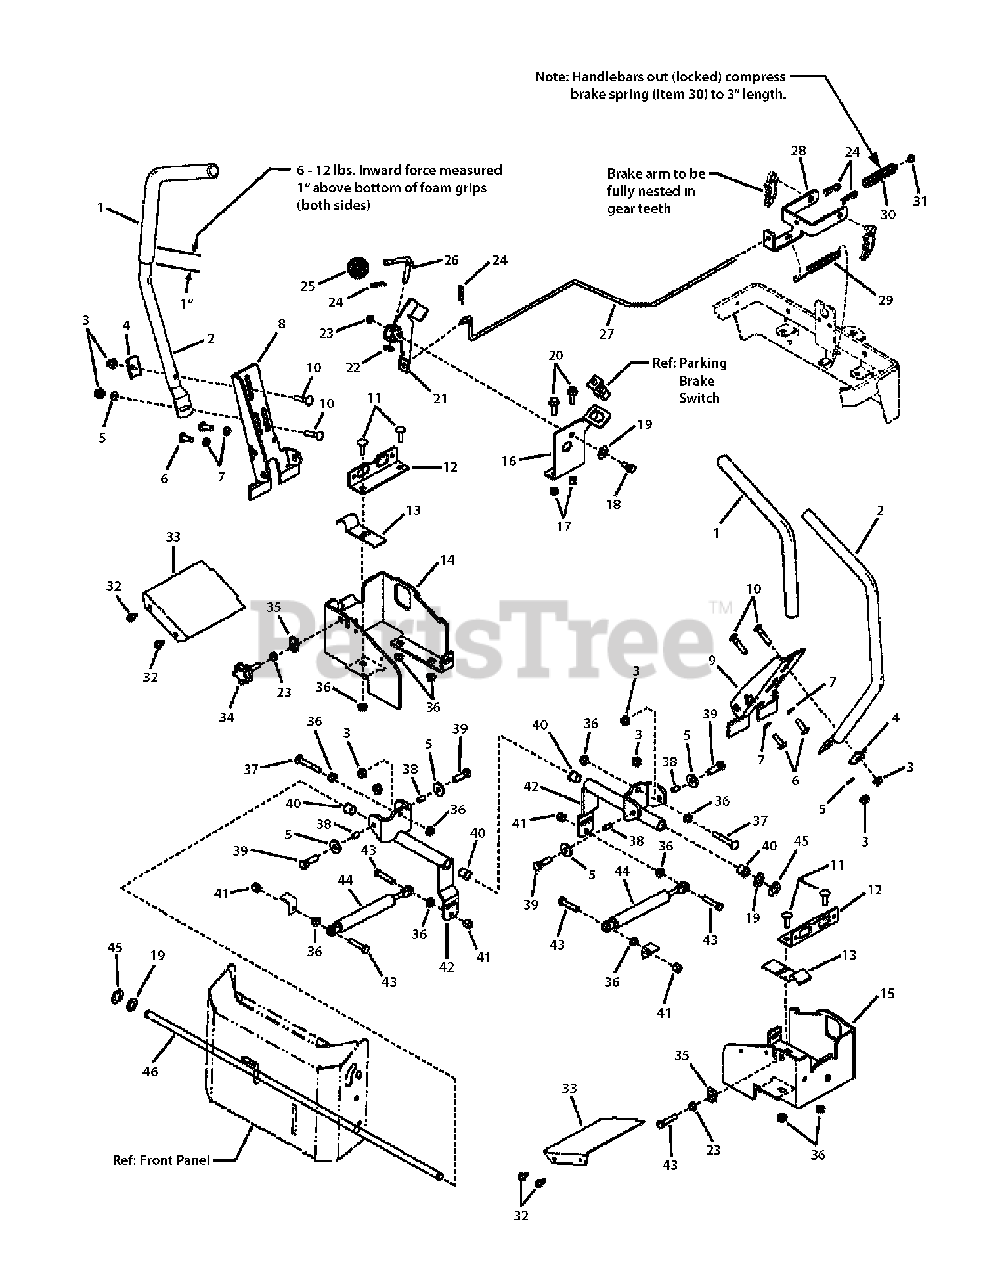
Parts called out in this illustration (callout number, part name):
1	GRIP, Foam Handle Bar
2	TUBE, Handle
3	NUT, 5/16-18 Hex Flange Nyloc
4	CLAMP, Tube, Saddle
5	WASHER, 5/16" Flat (.341 I.D. x 1.00 O.D. x .13 Thick) Black
6	SCREW, 5/16-18 x 7/8" Truss Head Torx, Black
7	LOCKWASHER, Spring 5/16", Black
8	BRACKET, Tube Mount LH
9	BRACKET, Tube Mount RH
10	BOLT, 5/16-18 x 1-3/4" Round Head Short Square Neck, GR5
11	BOLT, Carriage, Short Neck, 5/16-18 x 1
12	BRACKET, "L" Switch
13	CLIP, Brake
14	BRACKET, RH Mounting Handle Pivot
15	BRACKET, LH Mounting Handle Pivot, Black
16	BRACKET, Brake Pivot- ZT
17	NUT, 5/16-18-3B Hex Nyloc
18	SHOULDER BOLT, 5/16-18
19	WASHER, 1/2" Flat
20	BOLT, 5/16-18 x 1" Hex Flange Lock YZ
21	ARM, Brake Pivot- ZT
22	WASHER, .34 x .69 x .08 Flat
23	NUT, 5/16-18 Hex Jam, Black
24	HAIR PIN
25	KNOB, w/5/16-18 NILN (Brake/Clutch)
26	ROD, Park Brake- ZT (5/16-18 thread)
27	ROD, Manual Parking Brake (1/4-20 threads)
28	BRACKET, Dual Brake
29	SPRING, Extension
30	SPRING, Compression
31	NUT, 1/4-20 Hex Flange Nyloc, Black
32	SCREW, 1/4-20 x 1/2" Hex Washer Head Screw Black (Taptite)
33	COVER, Lower Handle
34	KNOB, 5/16-18 x 1-1/4" Extension Thread
35	NUT, 5/16-18 Speed (Lug Type .050/.200, Black)
36	NUT, 5/16-18 Hex Flange Lock, Small - Black
37	BOLT, 5/16-18 x 2-1/4" Round Head Square Neck, GR5, Black
38	SPACER, Powdered Metal
39	SCREW, 5/16-18 x 1-1/4" Hex Head Cap, GR5, Black
40	BUSHING
41	NUT, Hex Lock ESNA Light, 5/16-18
42	WELDMENT, Pivot Control
43	SCREW, 5/16-18 x 1-1/2" Hex Head Cap, GR5, Black
44	SHOCK ABSORBER
45	RING, Klipring Extension (for .500 Dia. Shaft)
46	SHAFT, Cross
